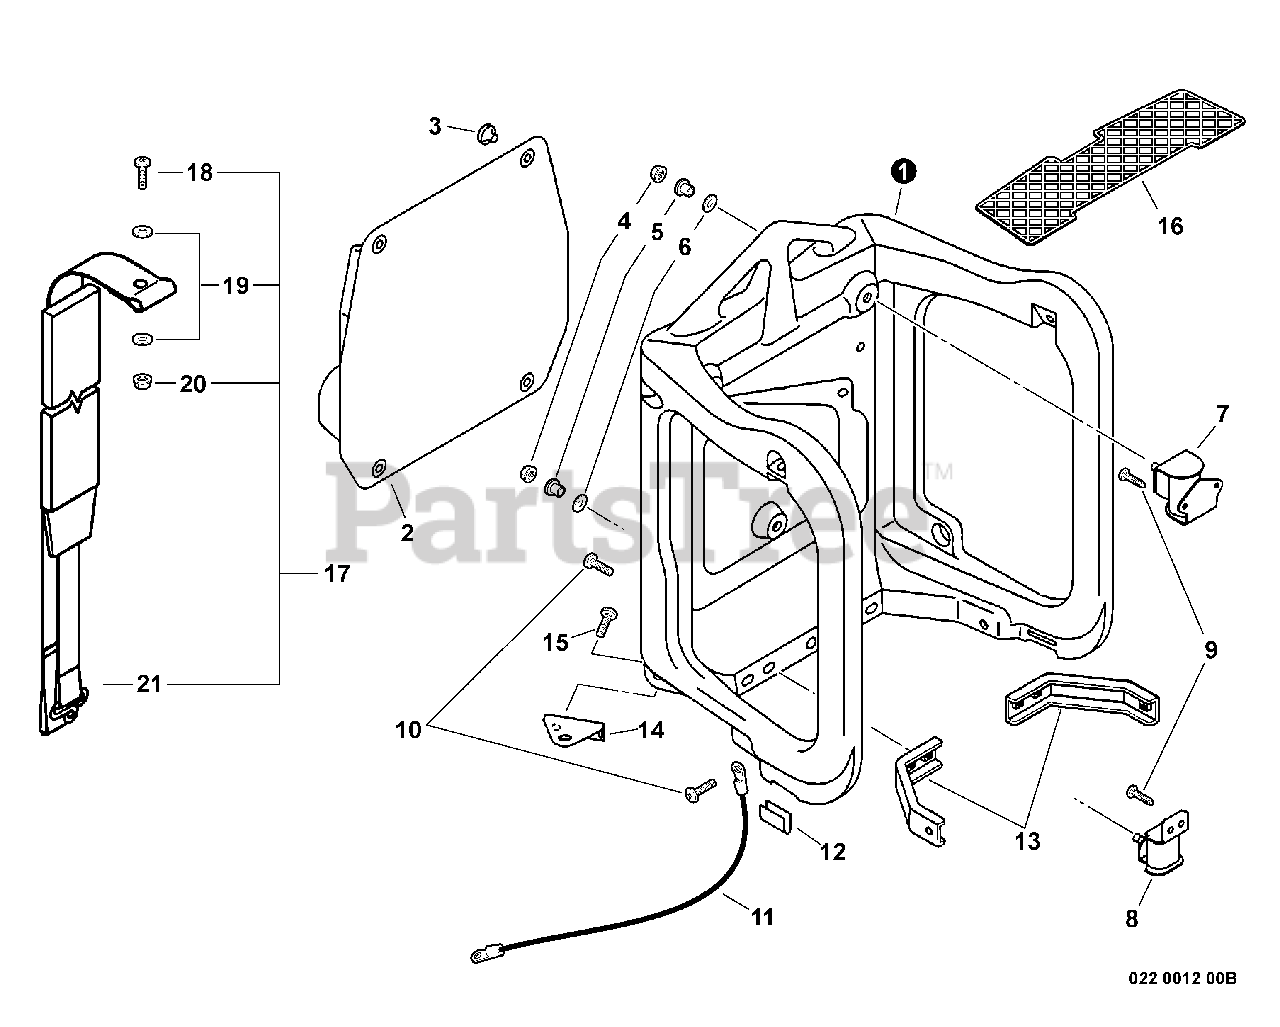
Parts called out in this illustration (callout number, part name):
1	FRAME, BACKPACK
2	CUSHION, BACKPACK
4	NUT - 5 -- FLANGE
6	WASHER - RUBBER
8	CUSHION
9	SCREW - 5X16 -- TAPPING
10	SCREW - 5X14
11	LEAD - GROUND
12	BUMPER
13	CONNECTOR, FRAME
14	BRACKET, HANGER
15	SCREW - 5X20
16	GAURD, DEBRIS
17	BACKPACK STRAP ASSY
18	SCREW - 5X14
20	NUT - 5 -- FLANGE
